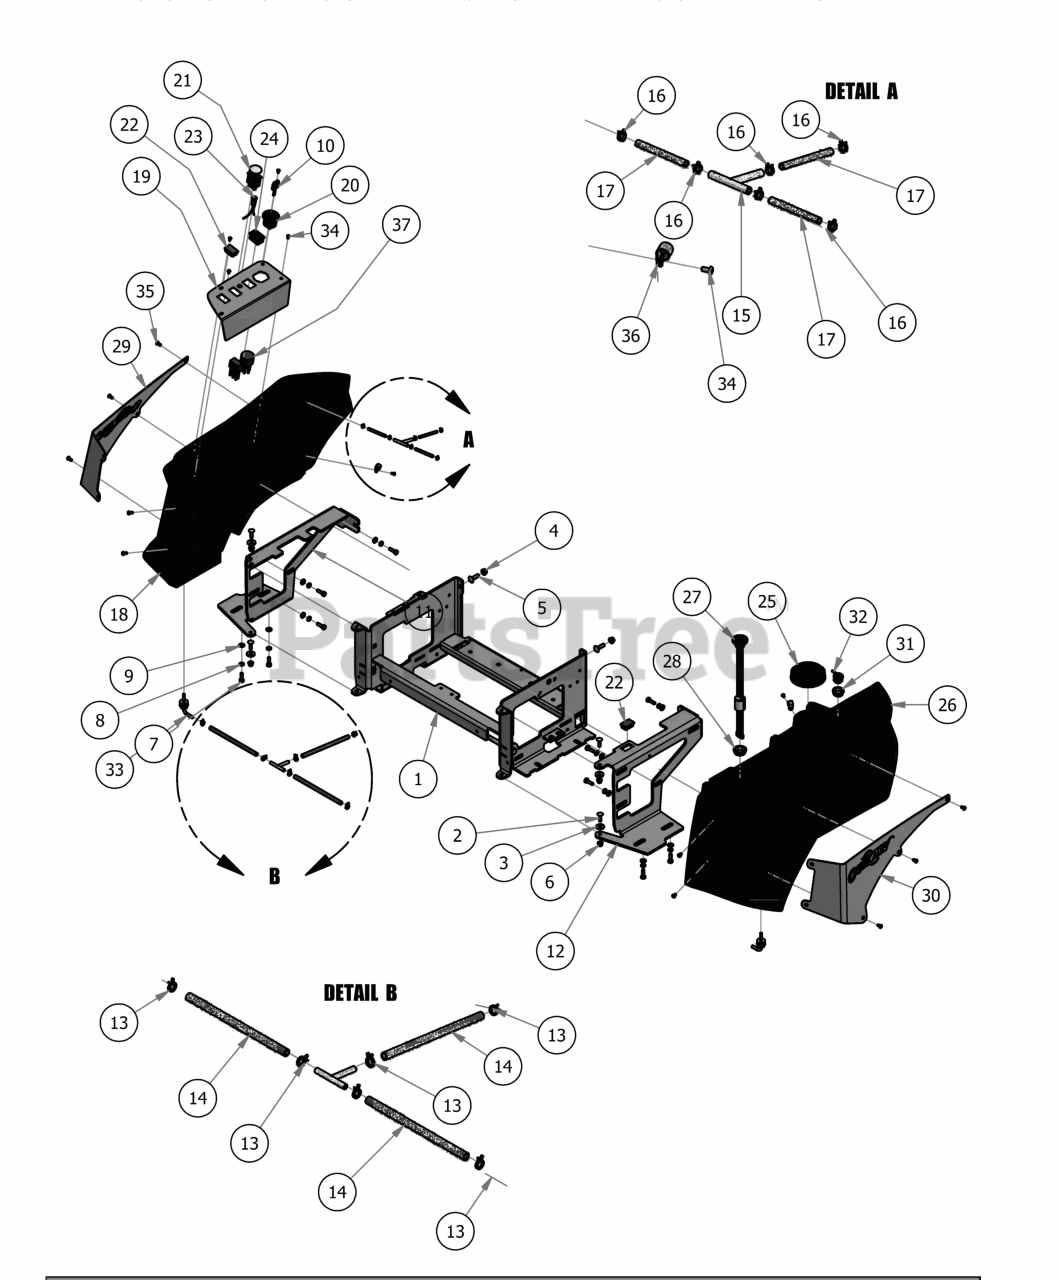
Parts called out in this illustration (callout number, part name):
1	2017 Outlaw Seat Bracket
2	5/16-18 x 1 Carriage Bolts Zinc
3	.360 ID Plastic Washer
4	3/8" Nylock Flange Nut
5	3/8" x 1 1/4" Carriage Bolt
6	5/16-18 Nylon Insert Flange Nut Zinc Orange Nylon
7	5/16" x 1" Bolt
8	5/16" Lock Washer
9	5/16" Flat Washer
10	Ignition Key
11	Outlaw 2015 Tank Support (Right)
12	Outlaw 2016 Tank Support (Left)
13	1/4 Fuel Hose Clamp
14	1/4" Fuel Line Hose
15	fuel line T
16	3/16 Vinyl Clamp
17	1/4" Vinyl Tubing
18	Outlaw 2015 Fuel Tank (Right)
19	Analog Control Panel Outlaw
20	Ignition Switch
21	PTO Switch
22	Light Plug
24	Tachometer
25	Fuel Cap (Kelch)
26	Outlaw 2015 Fuel Tank (Left)
27	Fuel Gauge w/Grommet
28	Grommet for Fuel Gauge
29	Outlaw Tank Panel (Right)
30	Outlaw Tank Panel (Left)
31	ROV Grommet
32	Rollover Valve - Black
33	Fuel Tank Hose Nipple w/Filter
34	10-32 x 3/8" Button Socket Head Bolt
35	1/4" x 1/2" BS C/S 18-8 SS
36	3/8 Cable Clamp-Black Nylon
37	Wiring Harness
